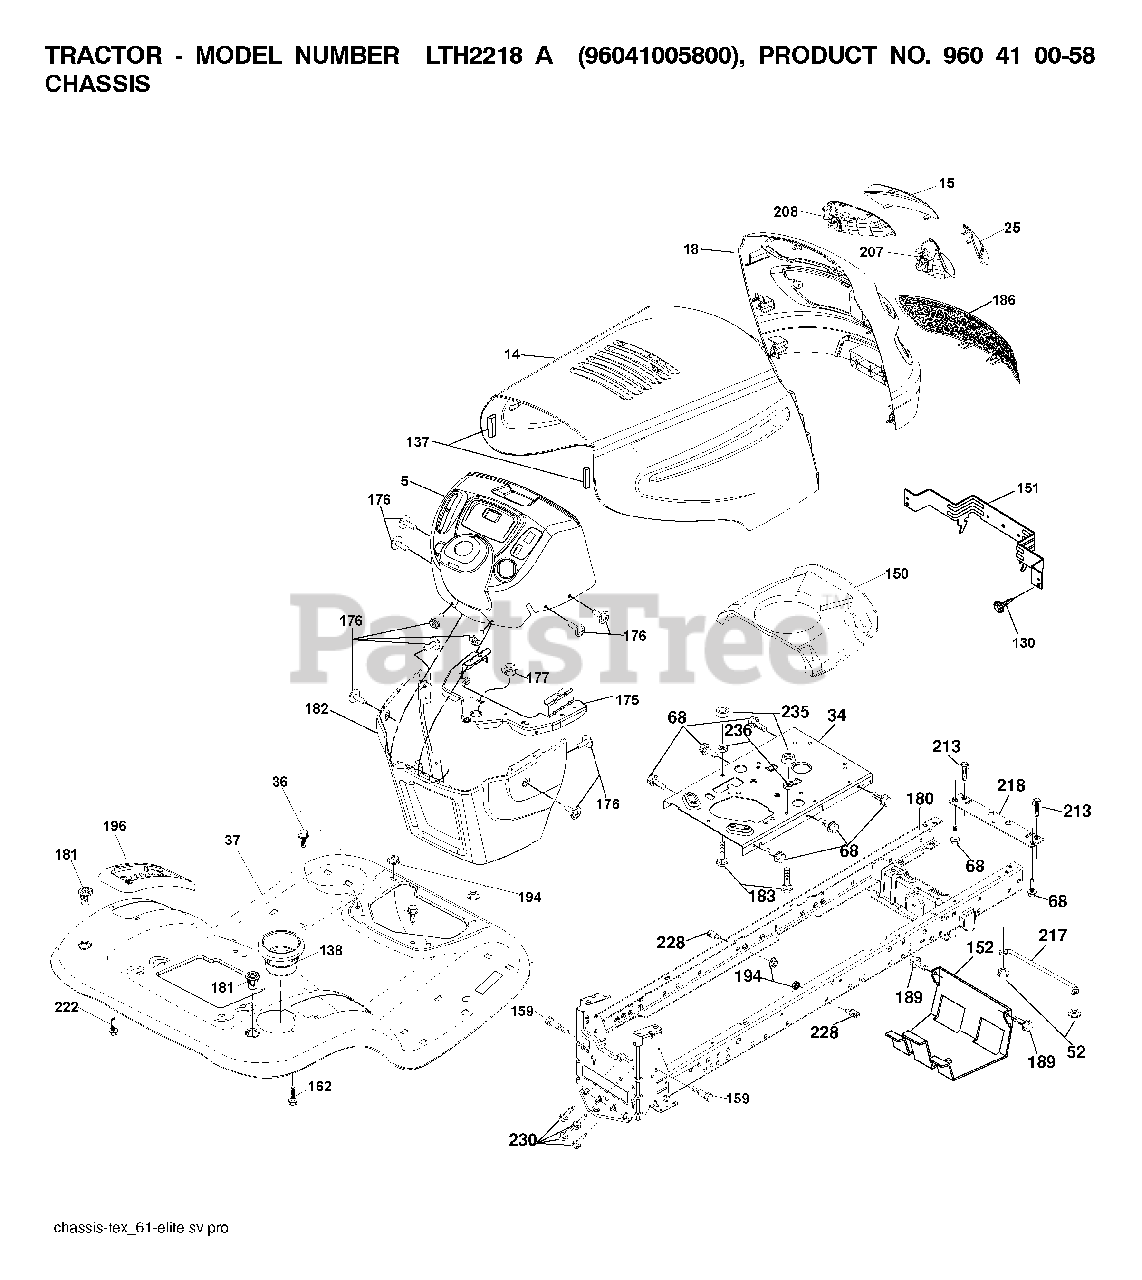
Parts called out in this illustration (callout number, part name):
34	PLATE.ENGINE.WELDED.CHASSIS
36	SCREW 5/16"
52	LOCKNUT
130	SCREW
137	BUMPER.HOOD.LARGE.1.75"
138	CUPHOLDER.TL.TEX.BLACK
151	BRACKET PIVOT
152	SHIELD BROWNING
159	SCREW, 3/8-16X3/4
162	SCREW.HI-LO.CONSOLE
175	CROSSMEMBER.LT
176	SCREW.#10-24X5/8.RN.QU
177	BUSHING STEERING
180	CHASSIS
181	FEND/FTRST.PCH.CPH.NFW
182	DASH.LOWER.LT.CCS
183	BOLT.5/16-18X1-1/4 FULL.THREAD
189	SCREW
194	NUT LOCK HEX FLANGE 5/16-18
196	CONSOLE.ASM.DECK.LIFT.TLT.BLAC
207	BEZEL GRILL RH
208	BEZEL GRILL LH
213	BOLT
217	ROD.PIVOT.HOOD
218	X-PIECE.HOOD.STOP.NON/
222	SCREW.1/4-20X5/8
228	STUD.FASTNER.W/ANTI-ROTATE
230	SHOULDER BOLT 5/16-18TT
235	SPACER FENDER
